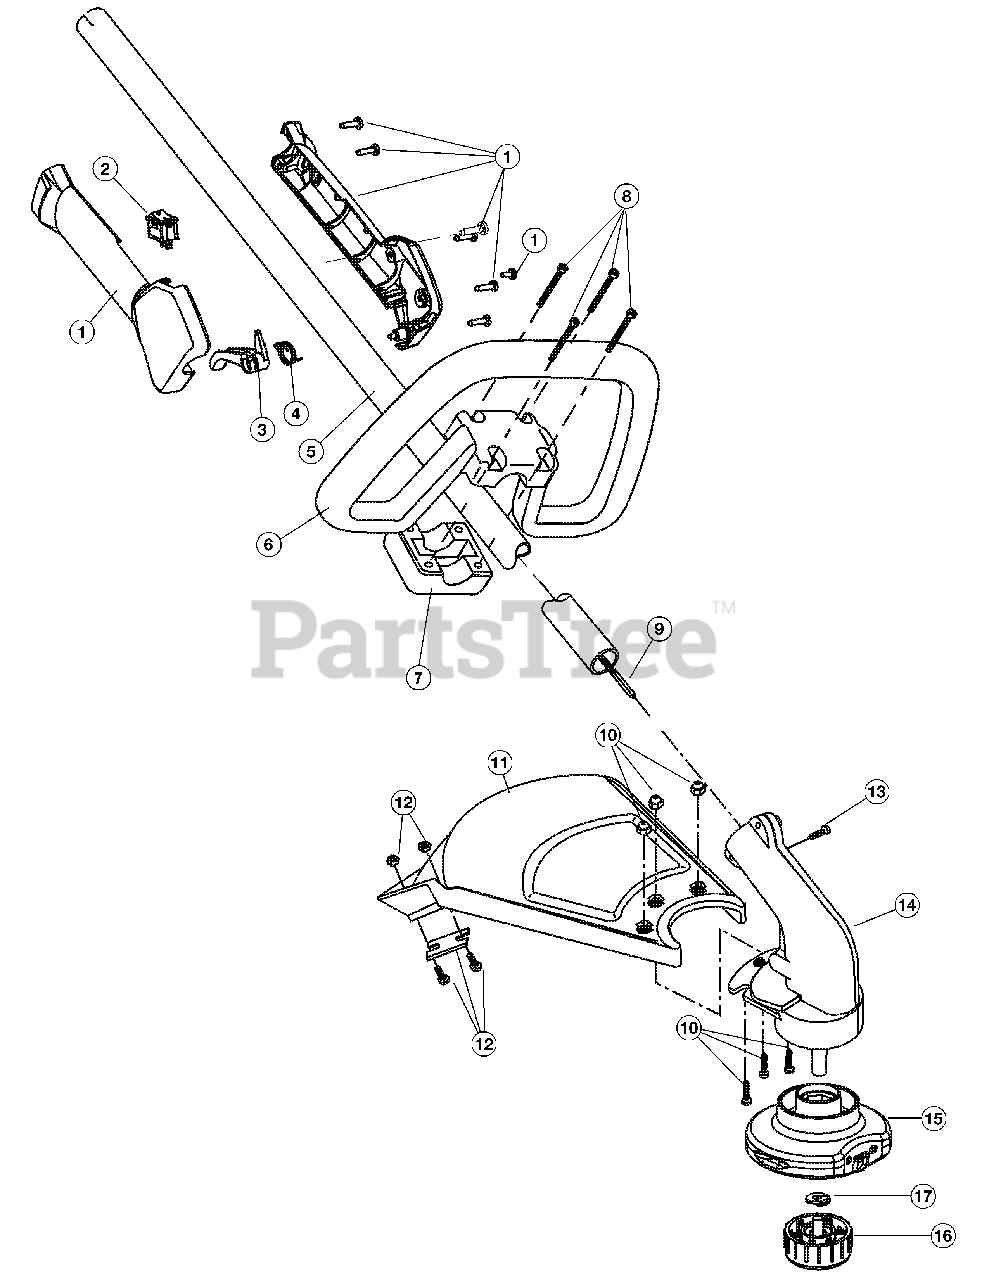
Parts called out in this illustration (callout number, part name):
1	Throttle Housing Assembly (Incl. 2-4)
3	Throttle Trigger
4	Throttle Trigger Spring
5	Drive Shaft Housing Assembly (Incl. 9)
6	D-Handle (Incl. 7&8)
7	D-Handle Base
9	Flexible Drive Shaft
10	Guard Mounting Screw Assembly
11	Guard Assembly (Incl. 13)
12	Blade Assembly
13	Anti-Rotation Screw
14	Gearbox Assembly
15	Fixed HD Line Assembly
16	Bump Head Knob Assembly
17	Lock Washer
